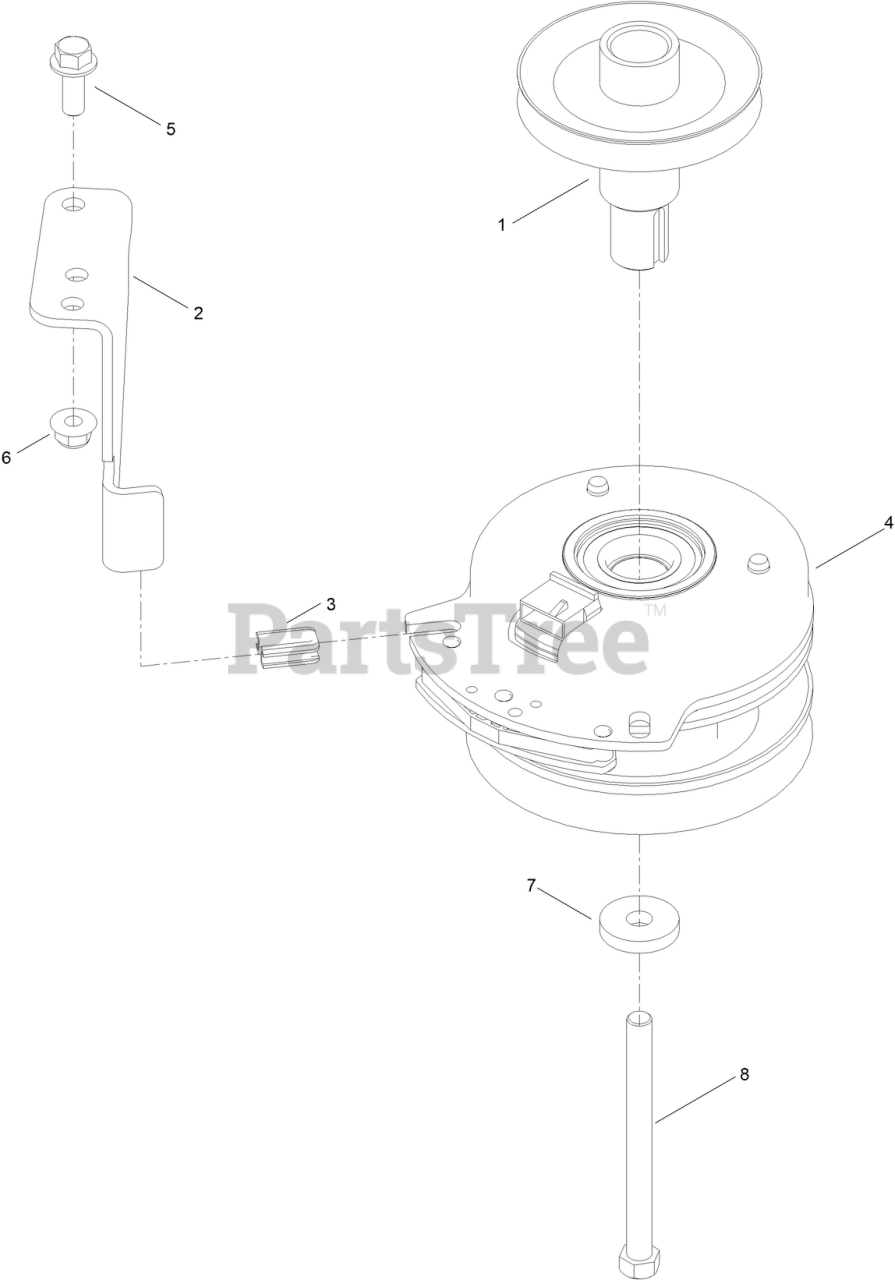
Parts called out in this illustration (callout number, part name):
1	PULLEY-ENGINE
2	STOP-CLUTCH (WIDE)
3	ISOLATOR-CLUTCH
4	CLUTCH-PTO
5	SCREW-HHF
6	NUT-HF, NI
7	WASHER
8	SCREW-HH
